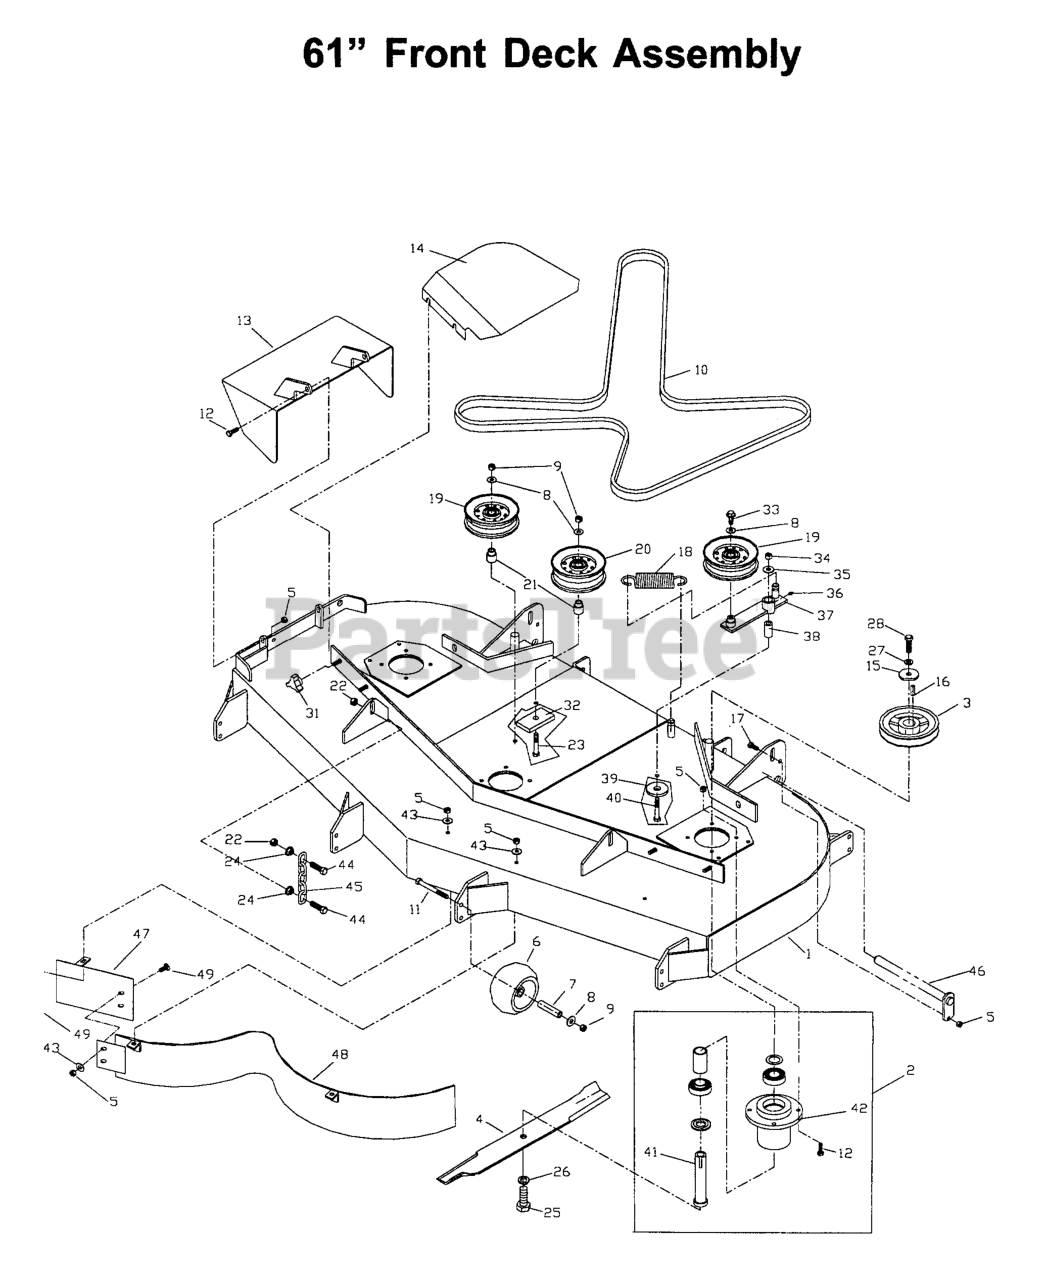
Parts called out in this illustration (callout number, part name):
1	DECK W/DECALS 61" HUS
2	HOUSING ASM.
4	BLADE OEM 21" (61" DECK)
5	NUT 5/16C CENTERLOCK
6	ANTI-SCALP ROLLER
8	WASHER 3/8 FLAT
9	NUT 3/8C CENTERBLOCK
10	DECK BELT 61
11	HCS 3/8C X 3 1/2
12	HCS 5/16C X 1
13	DISCHARGE CHUTE
14	61 B.S.PAINTED, RT
15	SPINDLE WASHER
16	KEY 1/4 SQ X 1 1/8
17	HCS 5/16C X 3/4
18	DECK SPRING
19	IDLER PULLEY
20	IDLER PULLEY (TALL)
21	IDLER BUSHING
22	NUT 7/16C CENTERLOCK
23	HCS 3/8C X 2 1/2
24	NUT 7/16C WHIZ
25	HCS 5/8F X 1 1/4
26	LOCKWASHER 5/8
27	WASHER 7/16 LOCK
28	HCS 7/16F X 1 1/2
31	KNOB, THREE PRONG
32	SUPPORT PLATE
33	4CS 3/8C X 1 SERRATED HEAD
34	NUT 1/2-13 HEX NYLOC ZD
35	WASHER 1/2 FLAT
36	ZERK
38	PIVOT BUSHING
39	WASHER, SUPPORT
40	HCS 1/2C X 3 1/4
42	HOUSING, DIE CAST
43	WASHER 5/16 FLAT
44	HCS 7/16C X 1 1/2
45	LIFT CHAIN
47	CENTER BAFFLE - 61
48	MAIN BAFFLE - 61" BLK
49	CARRIAGE BOLT 5/16C X 5/8"
539105103	61 B.S.PAINTED, LT ORANGE
539107406	BEARING KIT
